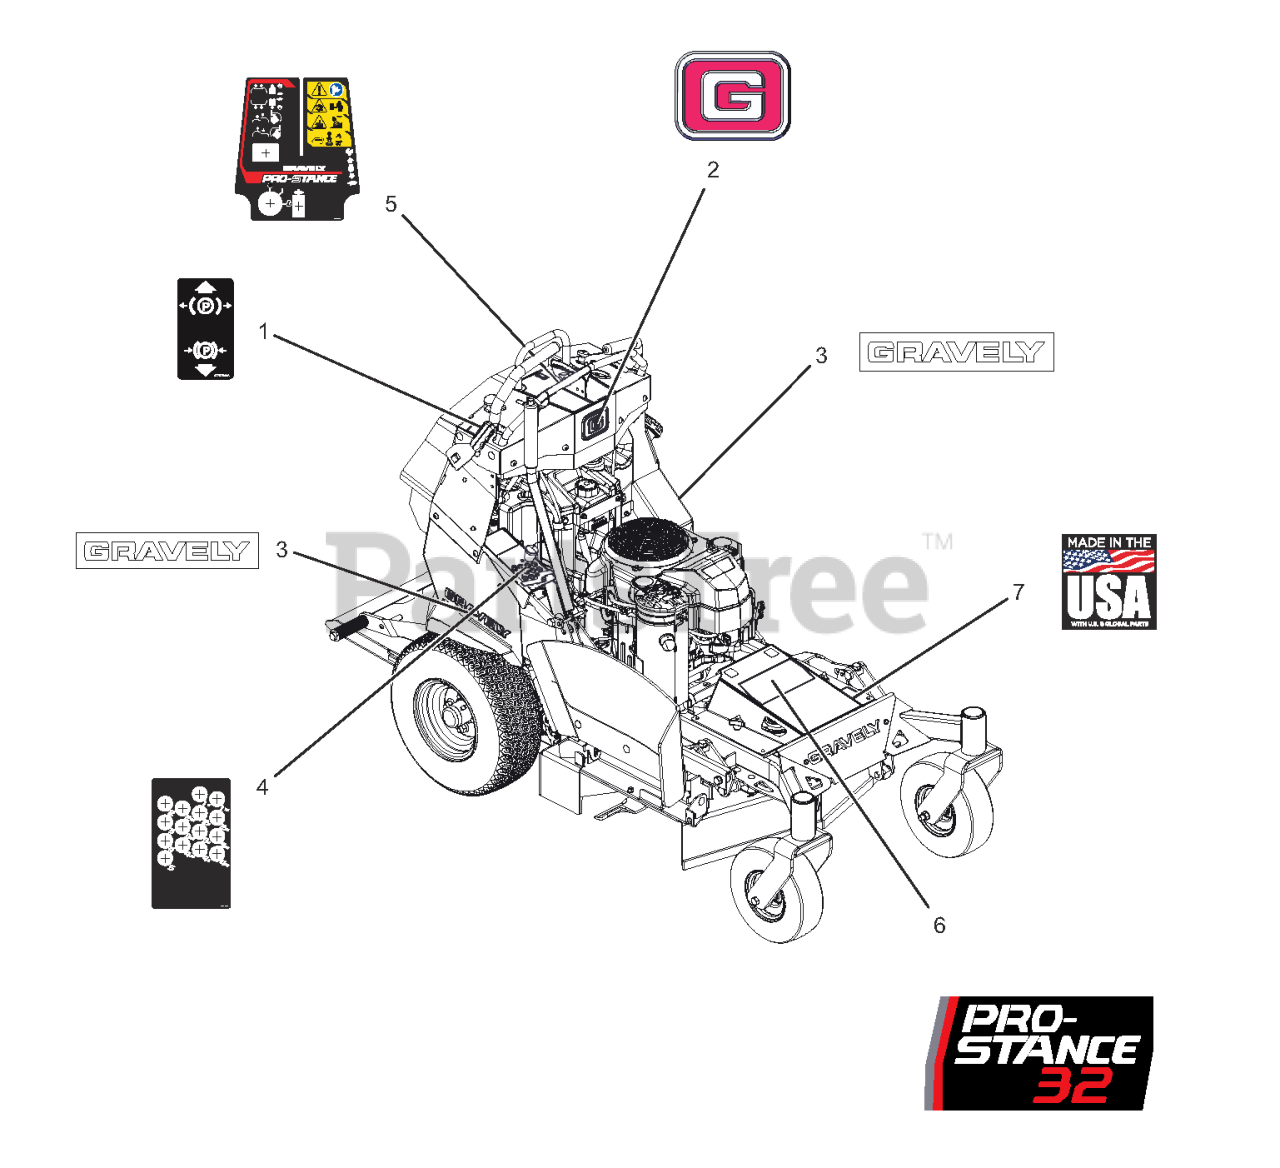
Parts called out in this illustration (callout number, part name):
1	DECAL, PARKING BRAKE LEVER
2	DECAL, GRAVELY BRAND
3	DECAL, 9.5" GRAVELY LOGO
5	DECAL, DASH - PROSTANCE
7	DECAL, MADE IN USA
